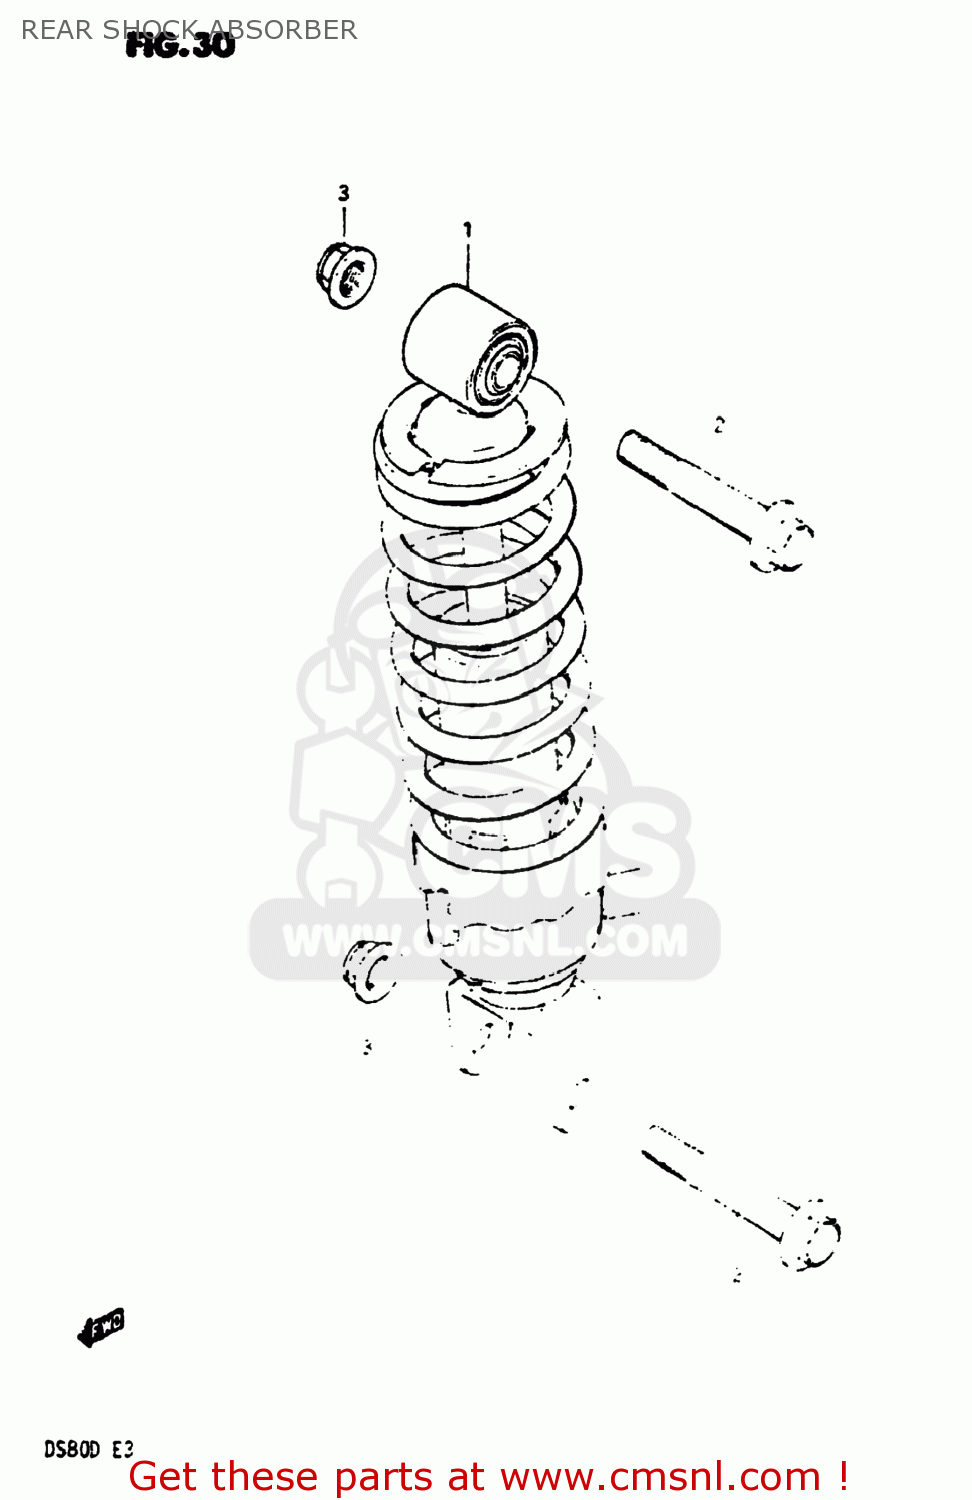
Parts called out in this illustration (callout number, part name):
1	ABSORBER ASSEMBLY,REAR SHOCK
2	BOLT,RR SHOCK ABSORBER(10X51)
3	NUT
